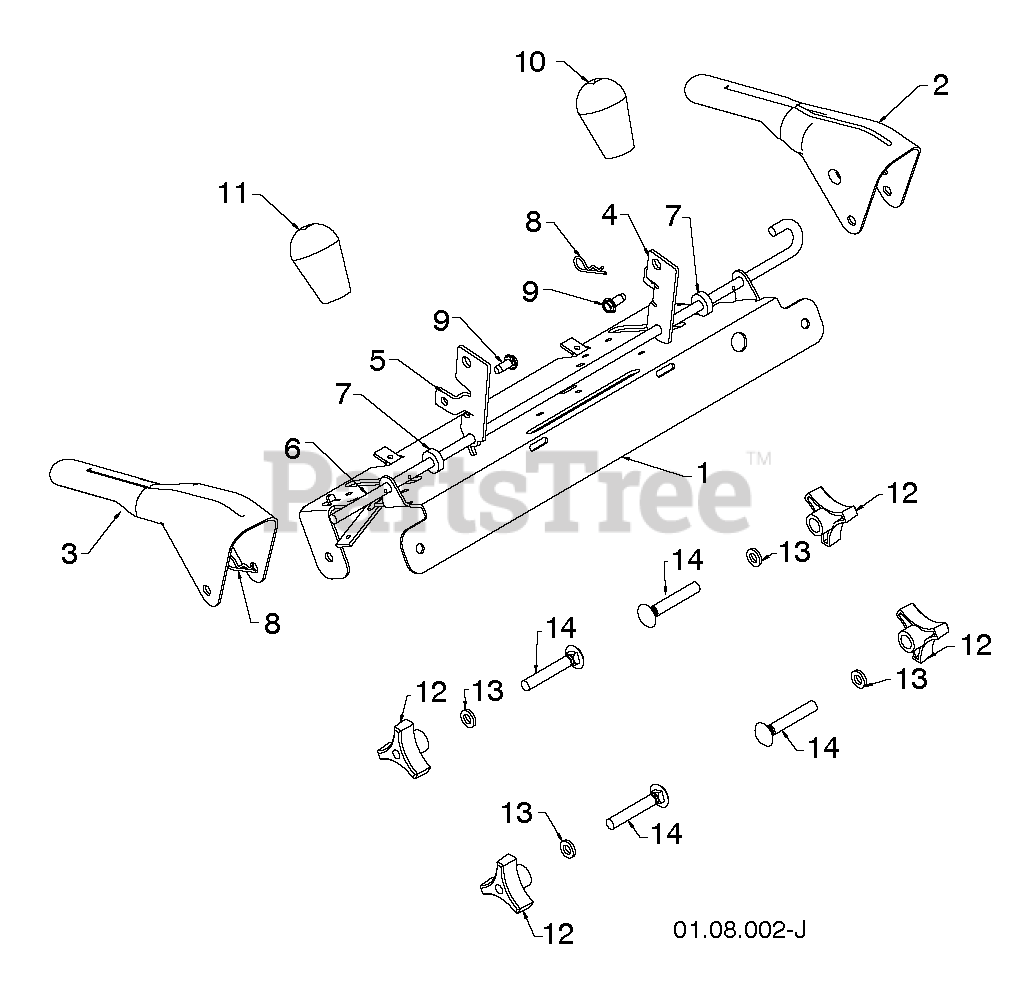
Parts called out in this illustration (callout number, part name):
1	PANEL.CONTROL.PNT.BLACK
2	LEVER.CONTROL.LH.BLACK
3	LEVER.CONTROL.RH.PNT.BLACK
4	ARM.TRACTION.ROD.YZ
5	ARM.IMPELLER.ROD.
6	BAIL.CONTROL.INTERLOCK
7	SPACER.CONTROL.LEVER
8	SPRING RETAINER
9	SCREW 14-20 X 5/8
10	KNOB LEVER, BLACK
11	RED KNOB SHIFTER
12	KNOB.HANDLE.3/8.TRI-POINT.BLAC
14	BOLT 3/8-16 X 2-1/4
